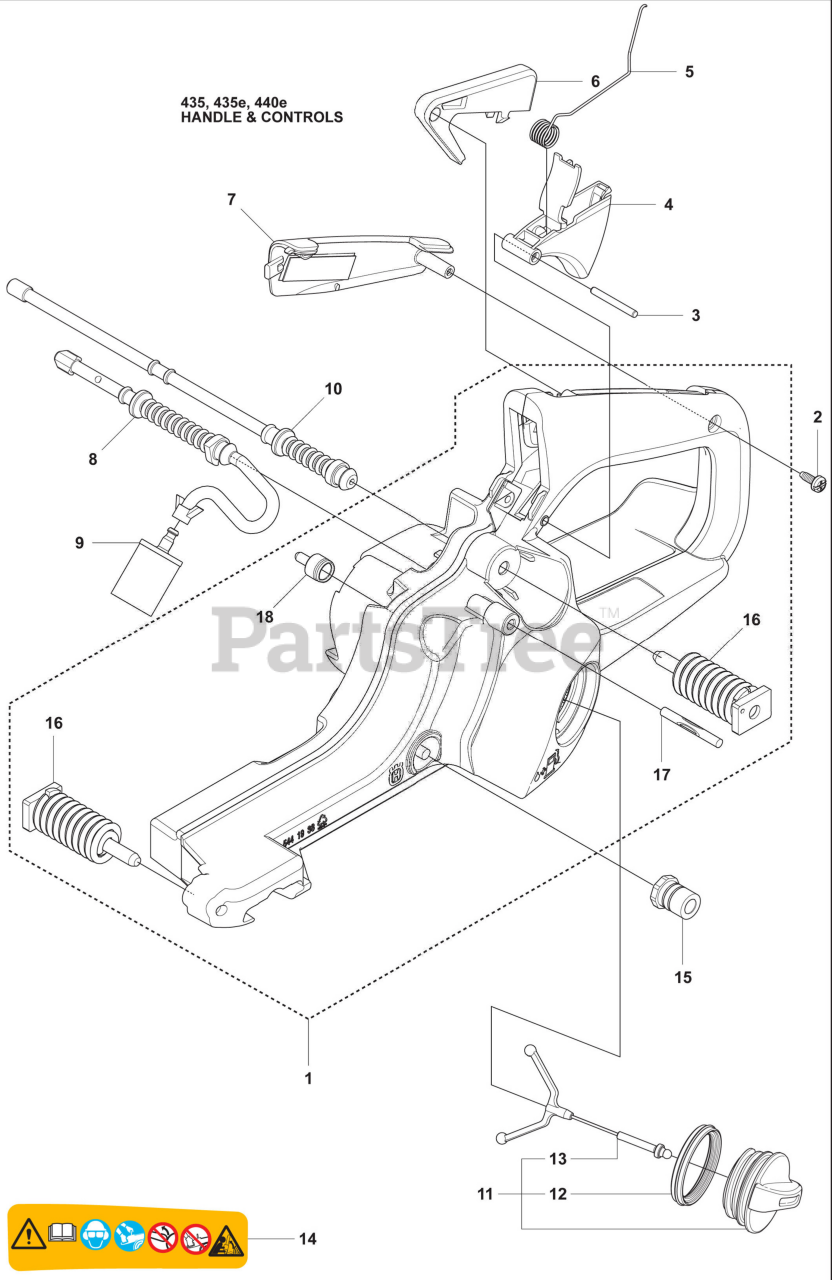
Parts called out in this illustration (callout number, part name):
1	Tank Fuel, Welded
2	Screw
3	Pin
4	Throttle Control
5	Spring
6	Trigger Lockout Grey
7	Handle Insert
8	Fuel Hose, RP
9	Fuel Filter Kit
10	Return Hose
11	Fuel Tank Cap Assembly, Grey
12	Sealing Gasket
13	Holder
14	Label
15	Lateral Support
16	Anti-Vibration Element
17	Grooved Pin
18	Tank Vent Assembly
